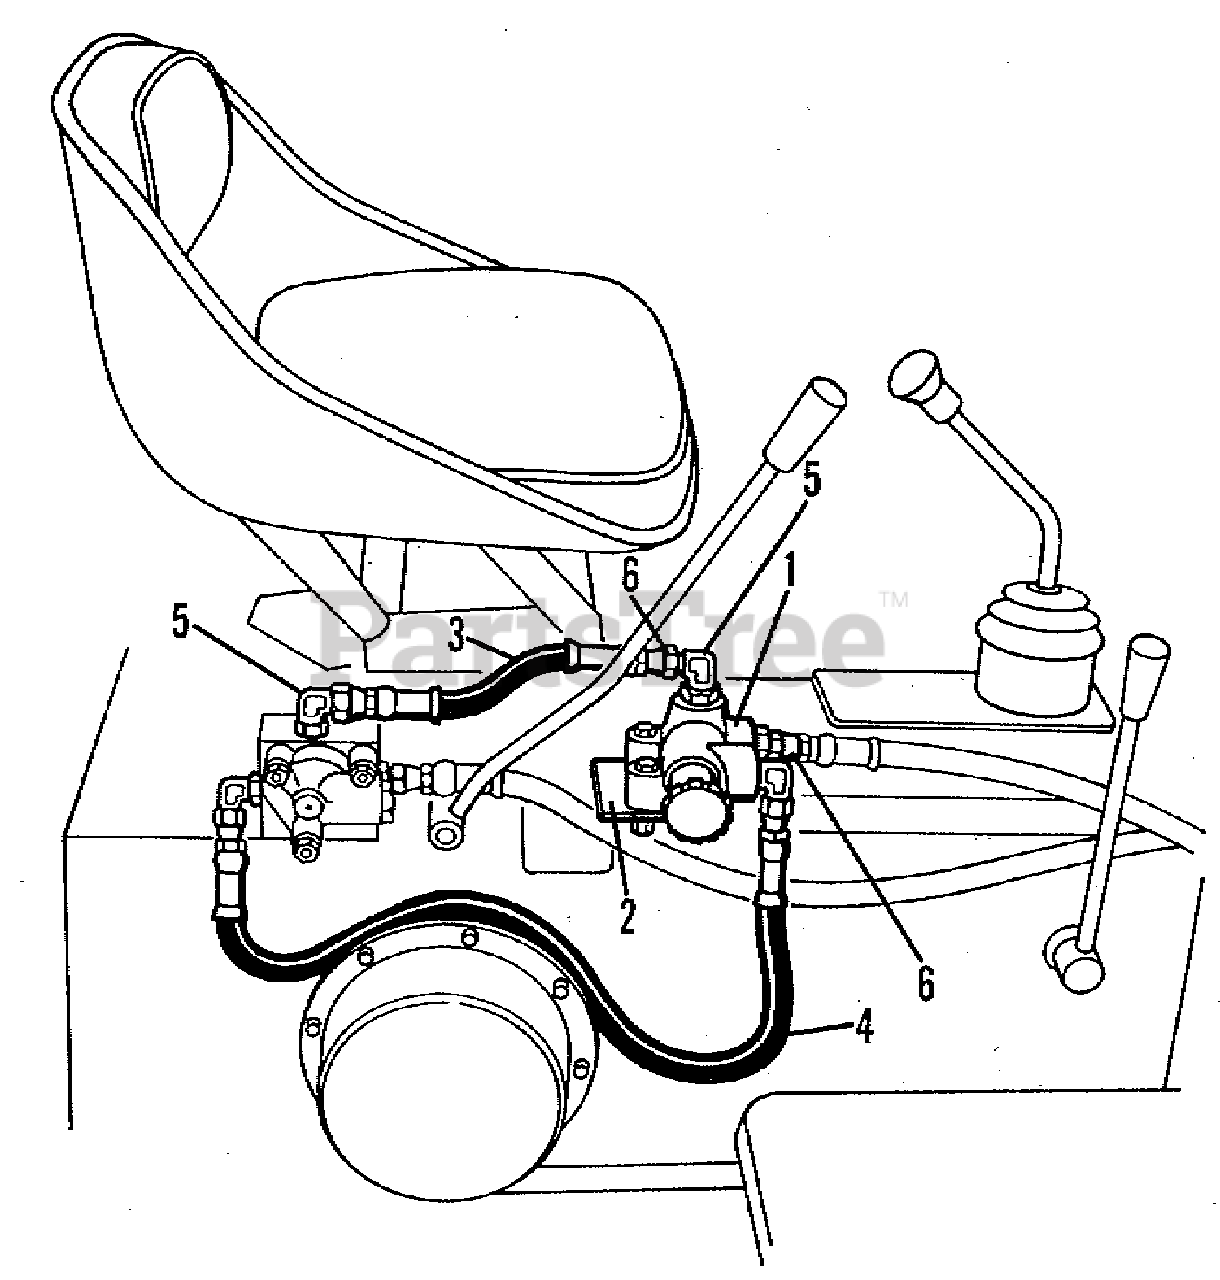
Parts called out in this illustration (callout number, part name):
1	VALVE ASSEMBLY, Selector (Prior to S/N 1717)
1	VALVE ASSEMBLY, Selector (Eff. S/N 1717 & Up)
2	MOUNTING, Valve
3	HOSE ASSEMBLY, 9" Long (Selector Valve to Diverter Block)
4	HOSE ASSEMBLY, 28" Long (Selector Valve to Diverter Block)
5	ADAPTER, Elbow
6	CONNECTOR, Straight
